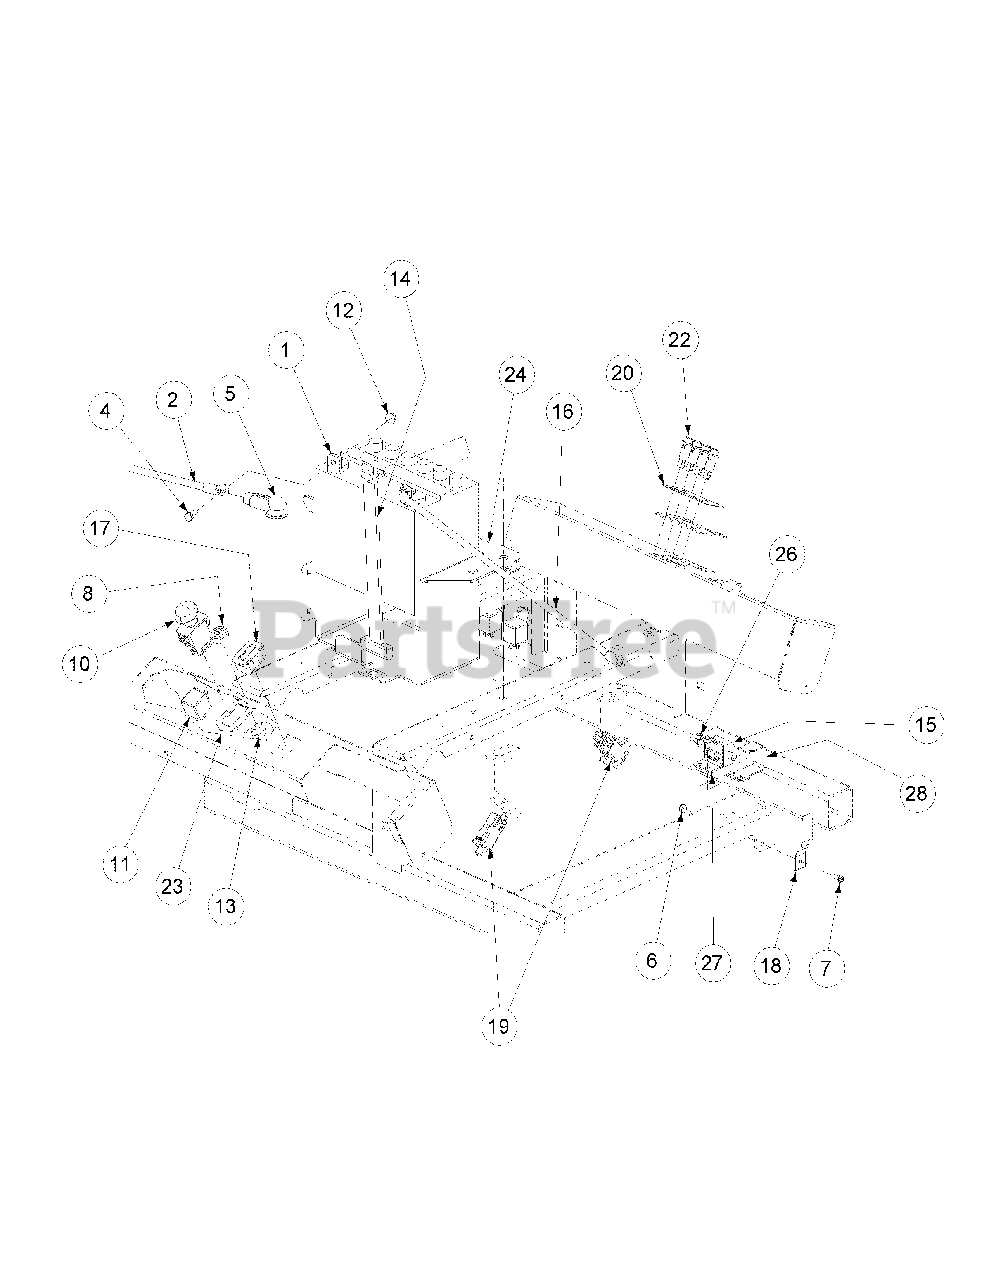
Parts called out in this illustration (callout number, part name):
1	Battery, 12V 225CCA 30 Min
2	Cable, Battery, Red, 36"
3	Tie, Cable, 3/16 x .05 x 7.4"
4	Screw, Hex, Cap, 1/4-20 x .75
5	Boot, 1" OD Rubber Battery-PST, Red
6	Nut, Lock, Nylon Insert, #10-32
7	Screw, Hex Washer, 10-32 x 1/2
8	Nut, W/Cap, 5/8-32 Ignition
10	Switch, Electric, PTO
11	Relay, 12V 40A
12	Hex Flange Lock Nut, 1/4-20
13	Switch, Ignition, 6 Pin
14	Strap, Battery
15	Switch, Plunger
16	Cable, Battery Black, 34"
17	Meter, Hour
18	Spring Retainer
19	Neutral Switch
20	Decal, Engine Light
22	Light Indicator, 12V
23	Bracket, PTO Switch Retainer
24	Mount Bracket, Battery
26	Self Tapping Screw, 1/4-20 x .50
27	Bracket, Plunger Switch
28	Clamp, Plunger Switch
